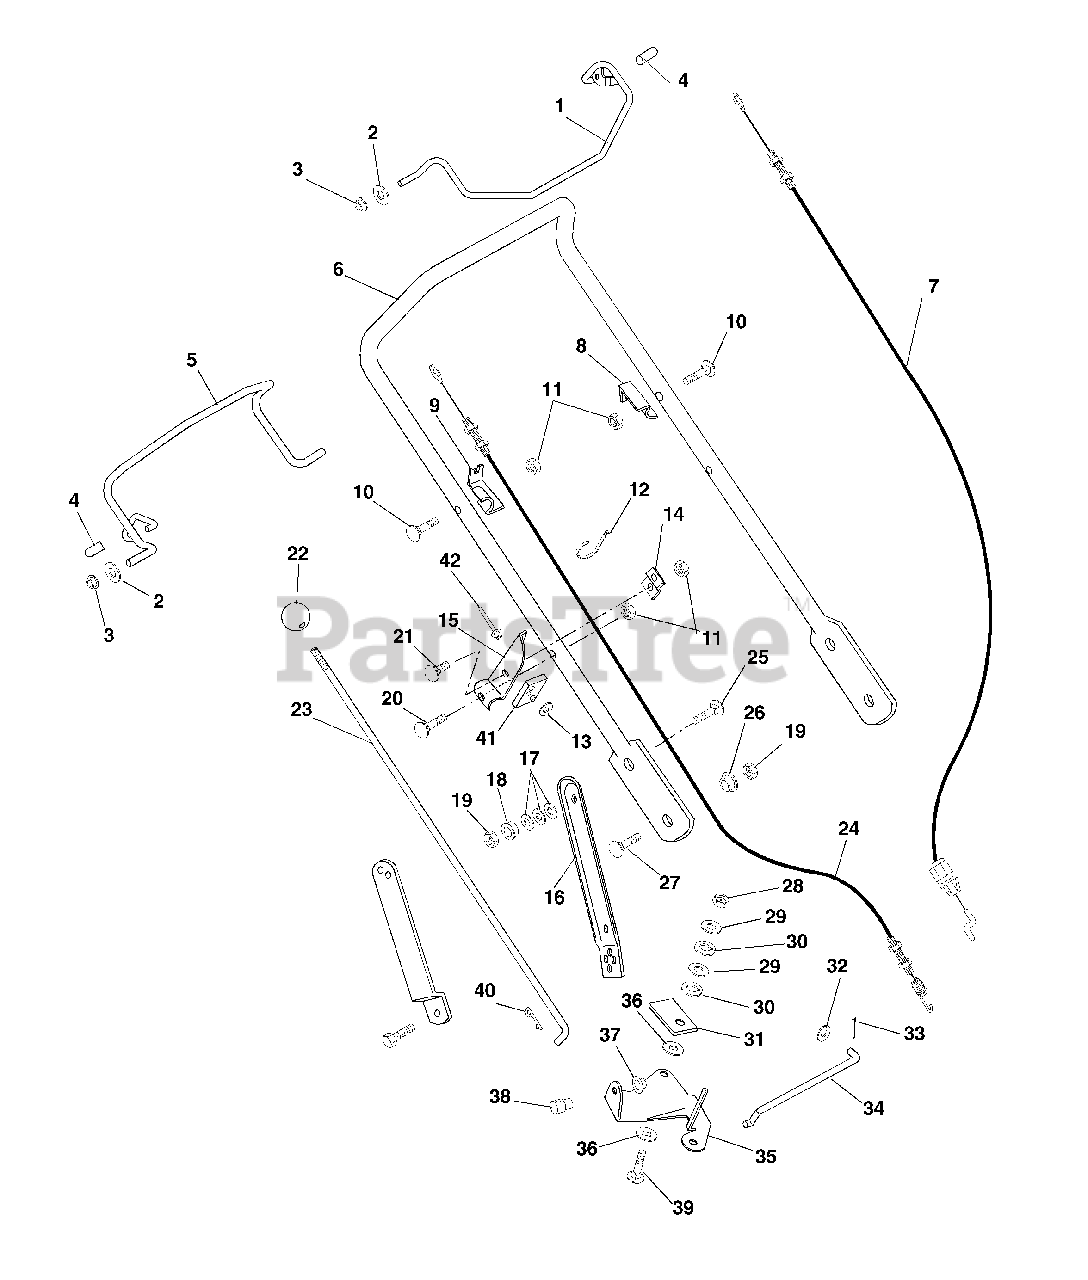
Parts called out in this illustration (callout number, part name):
1	ENGINE BAIL
2	@WSHR-FL-STL.344X.688X.065YWZC
3	BSHG-FLG .325X.444X.440X.560
4	CAP, VINYL, .25 ID
5	TRACTION BAIL
6	HANDLEBAR
7	ENGINE CONTROL CABLE
8	CABLE ANCHOR-LH
9	CABLE ANCHOR, RH
10	BLT-RDHDXLSQNK.25-20X1.25 G5ZC
11	@NUT-LK-CTR .25-20 YWZC
12	CABLE TIE LG 5-1/2
13	@WSHR-FL-STL.219X.50X.049 YWZC
14	BRACE, SPEED CONTROL
15	BRACKET, SPEED CONTROL
16	LINK, HANDLEBAR ADJUSTMENT LH
17	WASHER, BELLEVILLE YWZC
18	BSHG-FLG .325X.500X.513X.875
19	@NUT-LK-CTR .31-18 YWZC
20	@BLT-RDHDSQNK .25-20X1.50 G5YZ
21	@BLT-RDHDSQNK .25-20X.50 G5YZ
22	KNOB, BALL 5/16-18 X 1.5
23	ROD-SPEED CONTROL
24	TRACTION CABLE
25	@BLT-RDHDSQNK .31-18X1.00 G5YZ
26	BSHG, FLG .325X.499X.26X.88
27	@BLT-RDHDSQNK .31-18X.75 G5YZ
28	@NUT-LK-CTR .38-16 YWZC
29	@WSHR-FL-STL.406X.812X.065 YWZ
30	WSHR-LK .375X.115 HVY YWZC
31	PRESSURE FLANGE
32	@WSHR-FL-STL.281X.62X.065 YWZC
33	@PIN-CTR .06X.50 EXTPRSQCT YWZ
34	SHIFT LINK
35	BELL CRANK - SPEED CONTROL
36	FRICTION WASHER
37	CAP, 3/8 ROD YWZC
39	@BLT-RHDSSQNK .38-16X1.25 G5YZ
40	PIN-HAIR INT .08X.18X1.18 YWZC
41	SUPPORT PAD
42	RVT .187X.575 DOME AL BLACK
